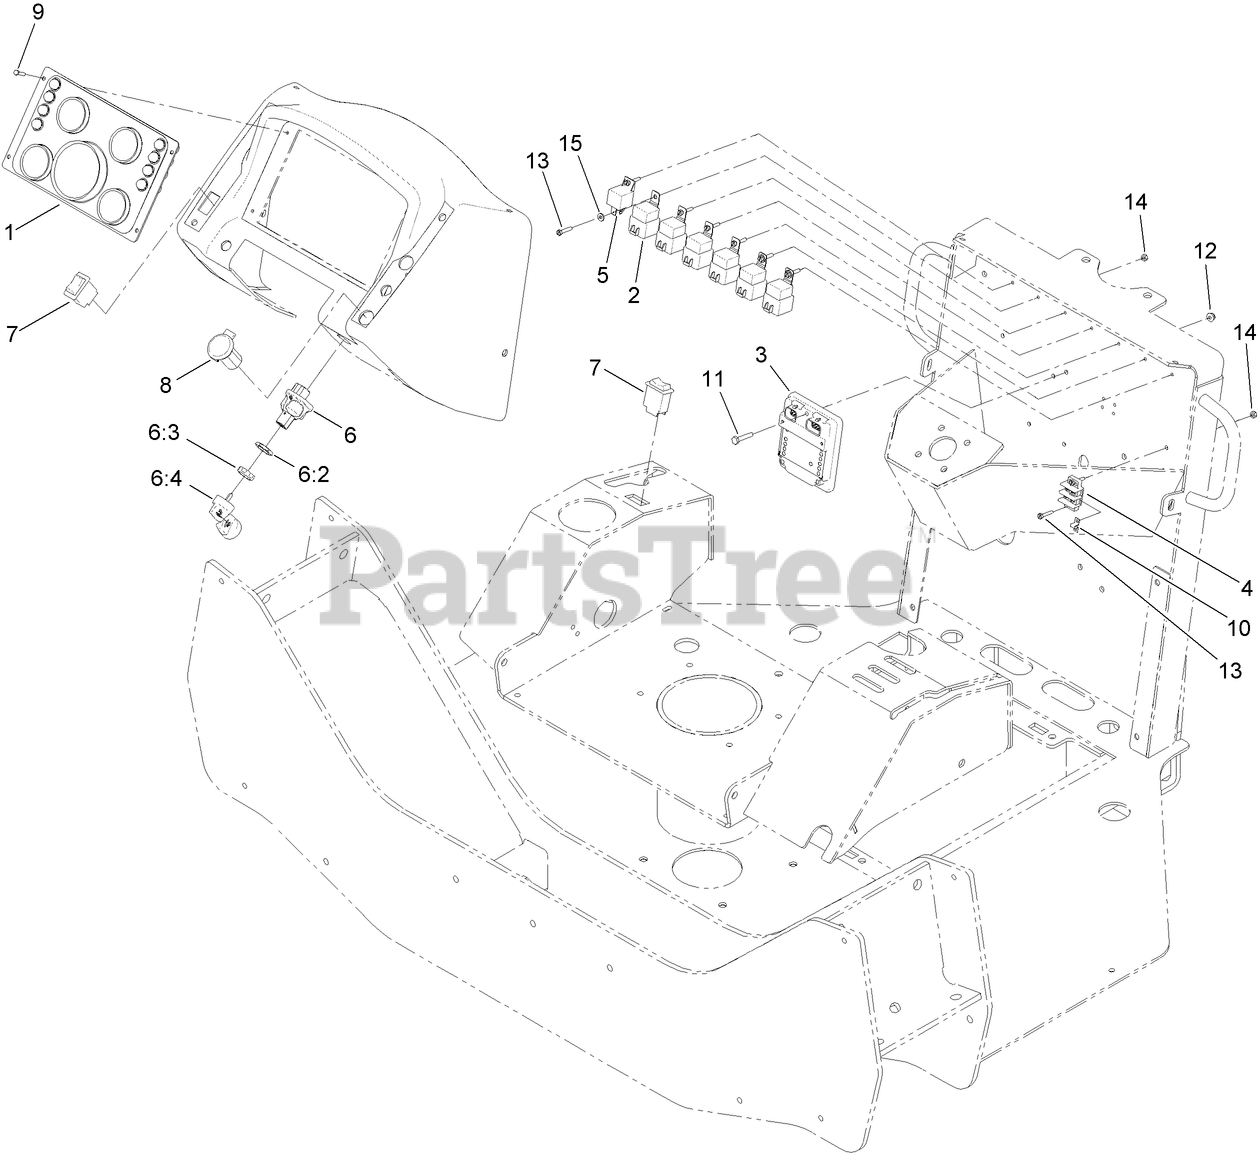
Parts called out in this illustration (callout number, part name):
1	INSTRUMENT PANEL ASM
2	RELAY
3	MODULE-CONTROL, STANDARD
4	BLOCK-TERMINAL, GROUND
5	RELAY-POWER
6	IGNITION SWITCH ASM
6:2	NUT-HEX
6:3	NUT-FACE
6:4	IGNITION KEY SET
7	SWITCH-ROCKER, 2 POLE (ON/OFF)
8	RECEPTICAL-12V DC
9	SCREW-HH
10	STRIP-JUMPER
11	SCREW-HH
12	NUT-HF
14	NUT-LOCK, NI
15	WASHER-FLAT
